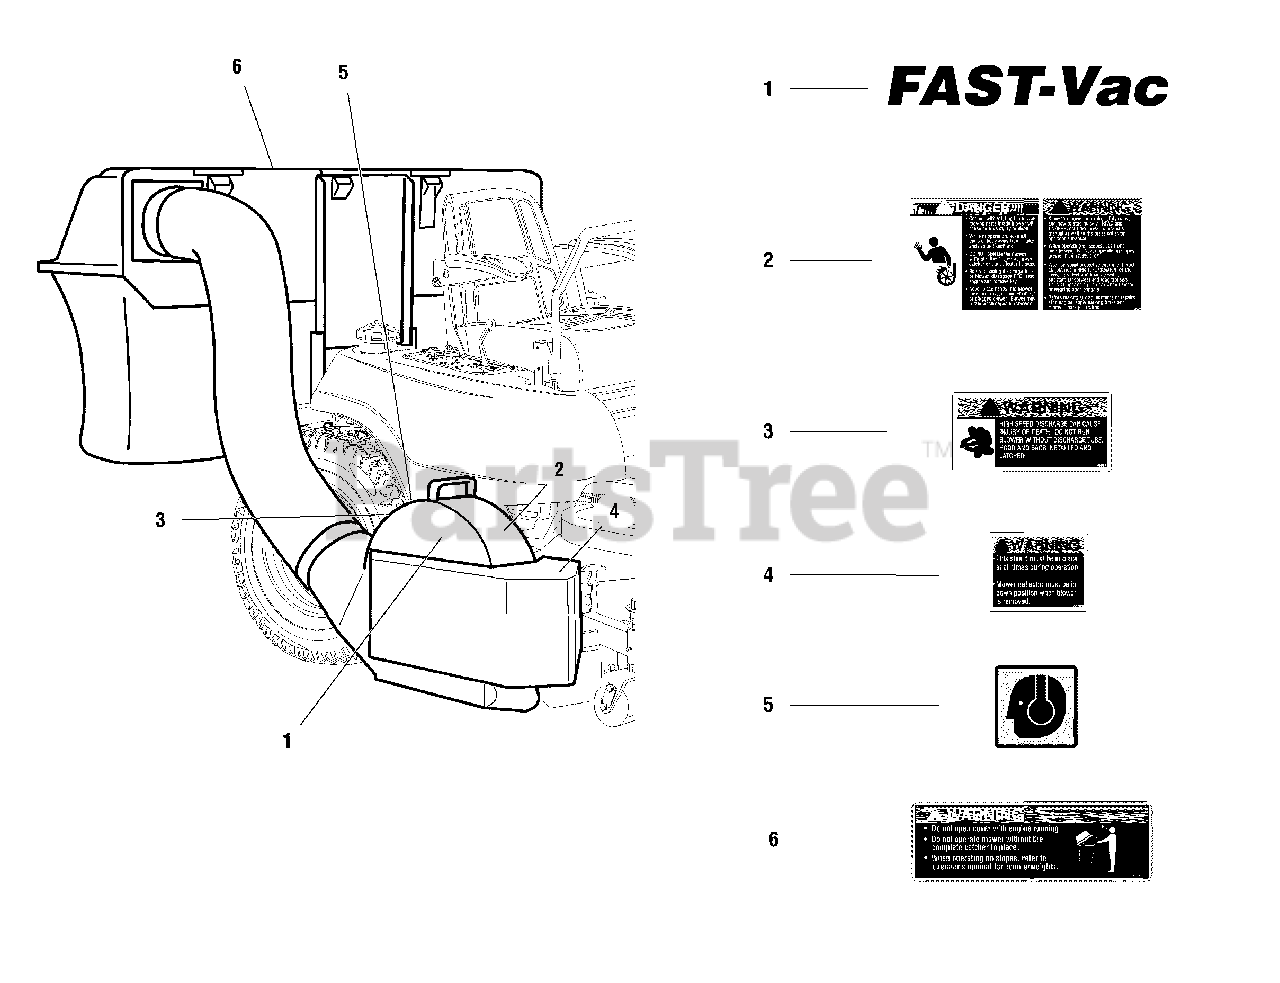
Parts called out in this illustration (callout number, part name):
1	DECAL, Fast-Vac
2	DECAL, Danger/Warning
3	DECAL, Warning-Blower
4	DECAL, Warning-Shield
5	DECAL, Ear Protection
6	DECAL, Safety
